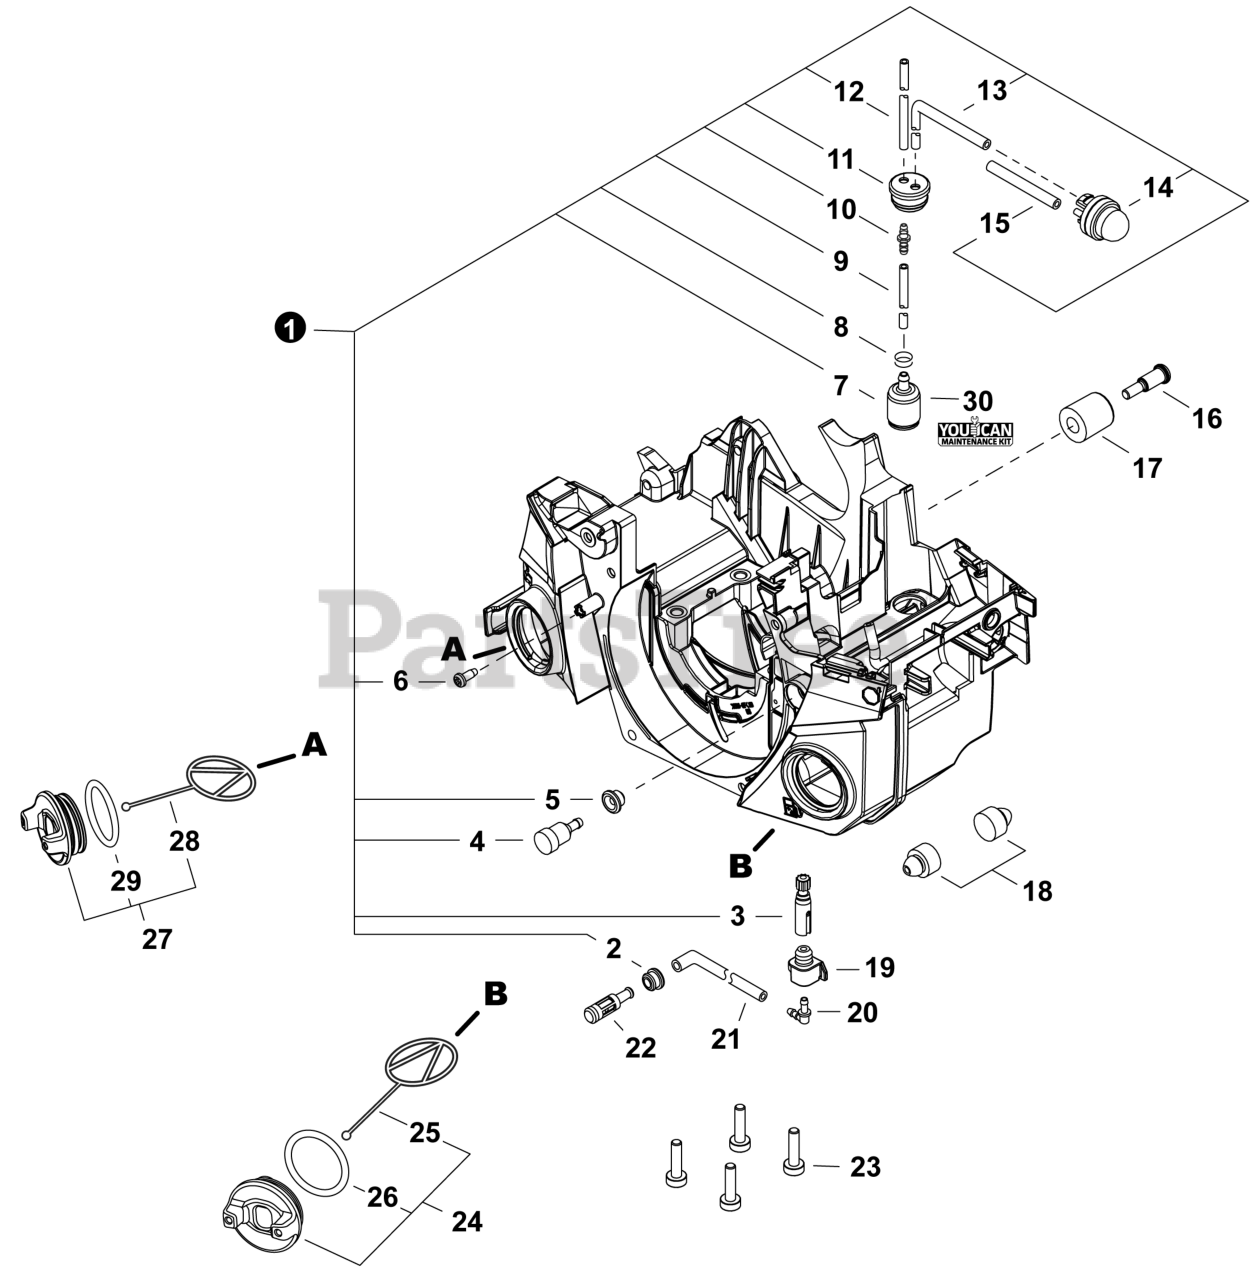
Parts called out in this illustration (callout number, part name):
1	HOUSING ASSY, ENGINE
3	AUTO-OILER ASSY
4	VENT ASSY
5	GROMMET, FUEL
6	SCREW, TAPPING 4x10
7	FILTER, FUEL
9	PIPE, FUEL 3x5x144 BLACK
10	CONNECTOR, PIPE
11	GROMMET, FUEL
12	PIPE, FUEL 3x5x65 BLACK
13	PIPE, FUEL 2.4x5x70
14	BULB, PURGE
15	PIPE, FUEL 2.4x5x90 BLACK
16	BOLT 5x12
17	CATCHER, CHAIN
18	CUSHION
19	GROMMET, OIL
20	CONNECTOR, PIPE
21	PIPE 3x6x210 BLACK
22	FILTER, OIL
23	BOLT, TORX 5x20
24	CAP ASSY, FUEL
25	CONNECTOR, CAP L= 60 MM
26	O-RING 29
27	CAP ASSY, OIL
28	CONNECTOR, CAP L= 60 MM
29	O-RING 29
30	TUNE-UP KIT - YOUCANT
